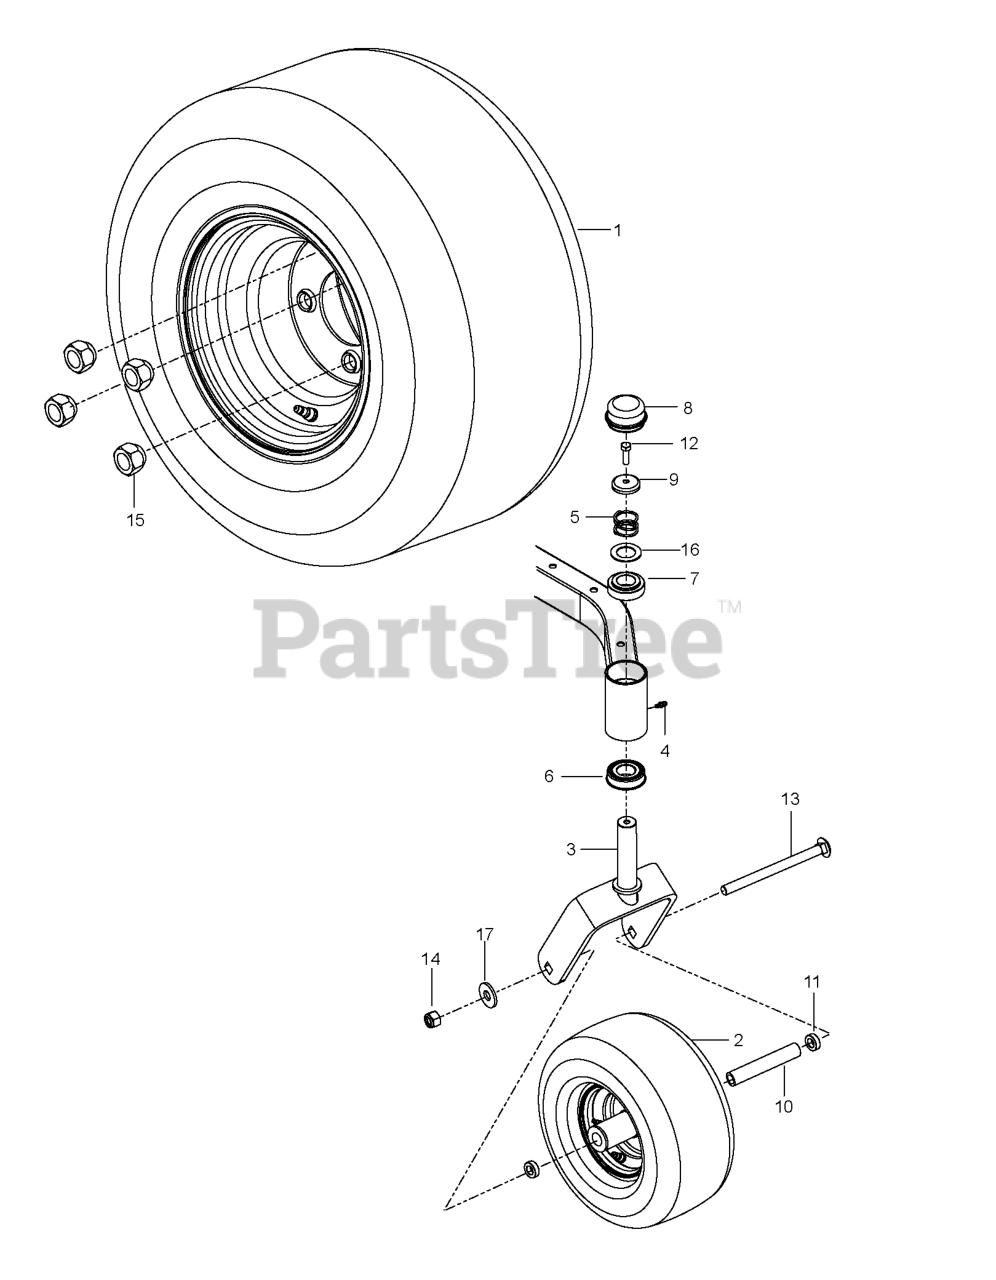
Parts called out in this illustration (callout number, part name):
1	WHEEL.ASSEM.18X8.5-8.KENDA.ZTR
2	WHEEL.CARLSTAR.11X4-5".MS417
3	YOKE.CASTER.ORANGE
4	ZERK, 3/16, DRIVE IN
5	SPRING, CASTER
6	BEARING FLANGED
7	BUSHING, CASTER
8	GREASE CAP
9	CASTER.PLUG
10	SPACER SPLIT
11	SPACER 5/16"
12	5/16-18X1 HHB G5W/NY
13	RHSNB 1/2-13 X 6.50 GR2 ZD
14	NUT 1/2-13 HEX CNTRLK GR 5 ZD
15	LUG NUT 1/2F
16	WASHER, 1.025 ID X 1.64
17	WASHER.9/16 X 1 3/8 X 12 GA.
